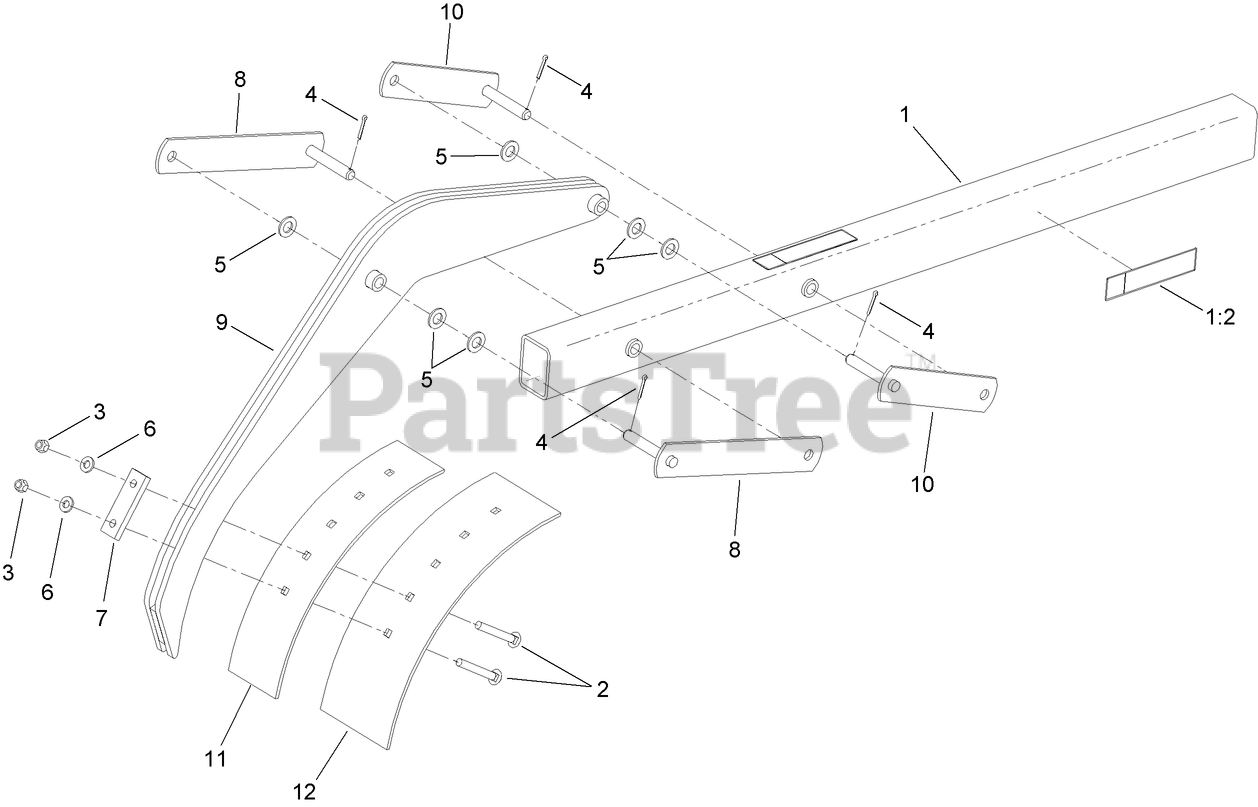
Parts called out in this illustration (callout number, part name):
1	5 FOOT CRUMBER TUBE ASM
1:2	DECAL-DANGER, ENTANGLEMENT
2	BOLT-CARR
3	NUT-HEX
4	PIN-COTTER
5	WASHER-FLAT
8	LINK-LONG, CRUMBER
9	ARM-CRUMBER
10	LINK-CRUMBER, SHORT
11	BLADE-MANUAL CRUMBER, 6 INCH CUT
12	BLADE-MANUAL CRUMBER, 8 INCH CUT
